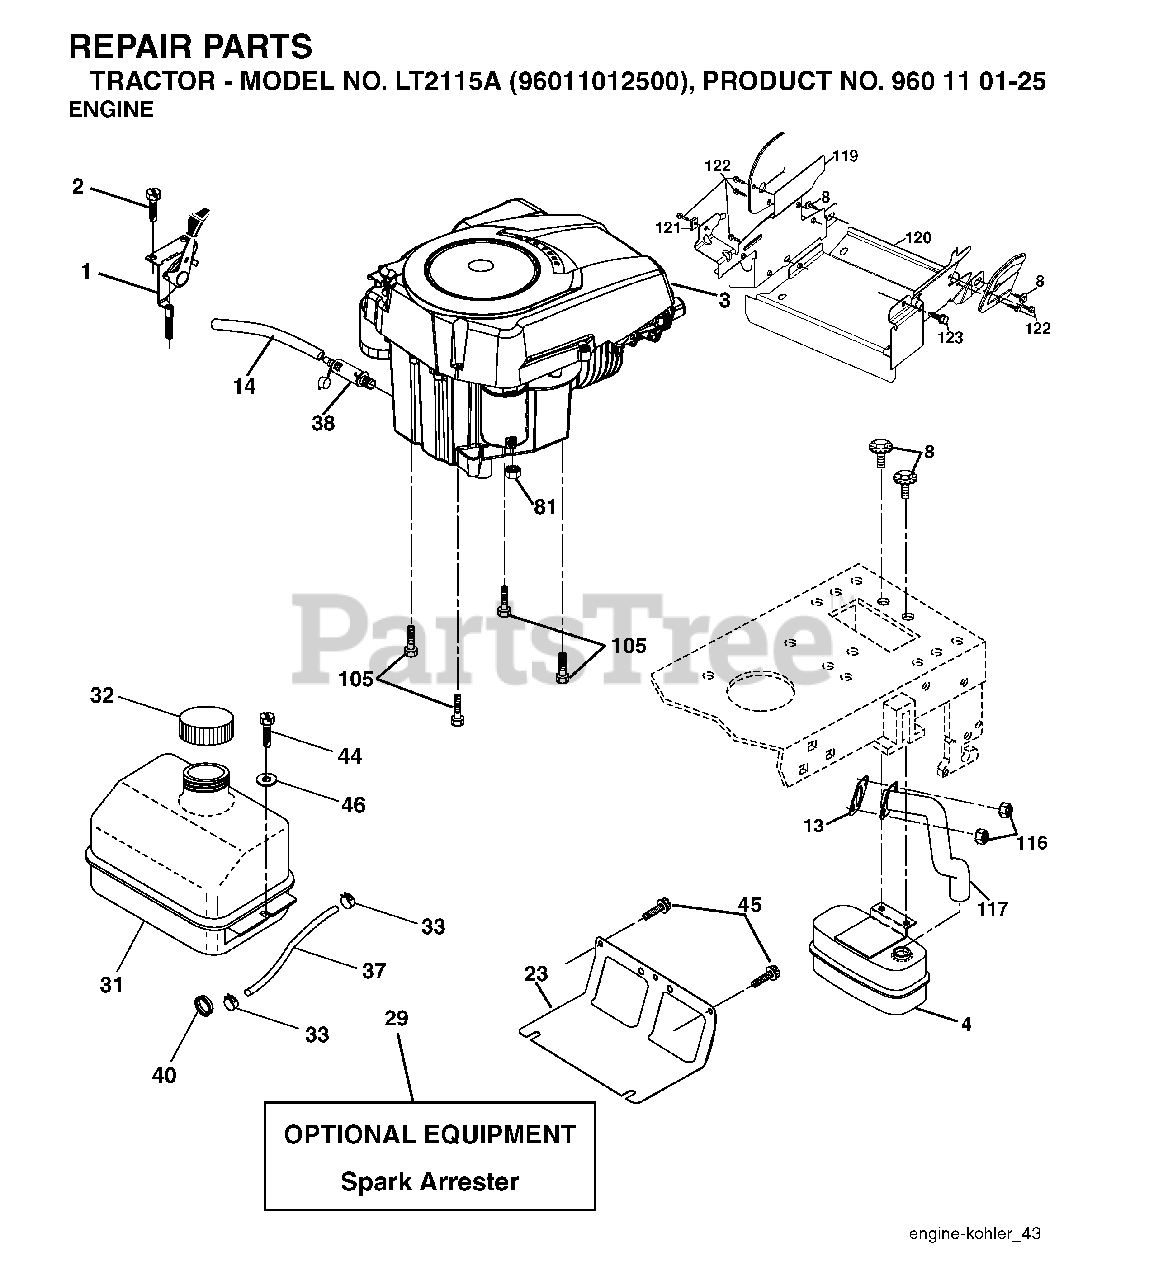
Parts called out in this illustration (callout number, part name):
1	CONTROL.THROTTLE.LT/YT
2	SCREW
4	MUFFLER.SINGLE.CYL.KOHL/B&S
8	BOLT, 5/16-18 X 1 3/4
13	GASKET ENGINE
14	TUBE, DRAIN OIL ASM.
23	SHEILD.BROWNING.DBR.GUARD
29	ARRESTER SPARK (OPTIONAL)
31	TANK FUEL FRONT
32	FUEL CAP
33	HOSE CLAMP
37	LINE.FUEL.20
38	PLUG DRAIN OIL EASY
40	GROMMET T
44	SCREW HEXWSHR 1/4-20X3/4
45	SCREW, 3/8-16X3/4
81	NUT
105	SCREW 3/8-16X1
116	NUT.HEX.FLANGE.TOPLOCK
117	TUBE EXHAUST
122	SCREW.1/4-20X5/8
123	SCREW, 5/16-18 X 1/2
